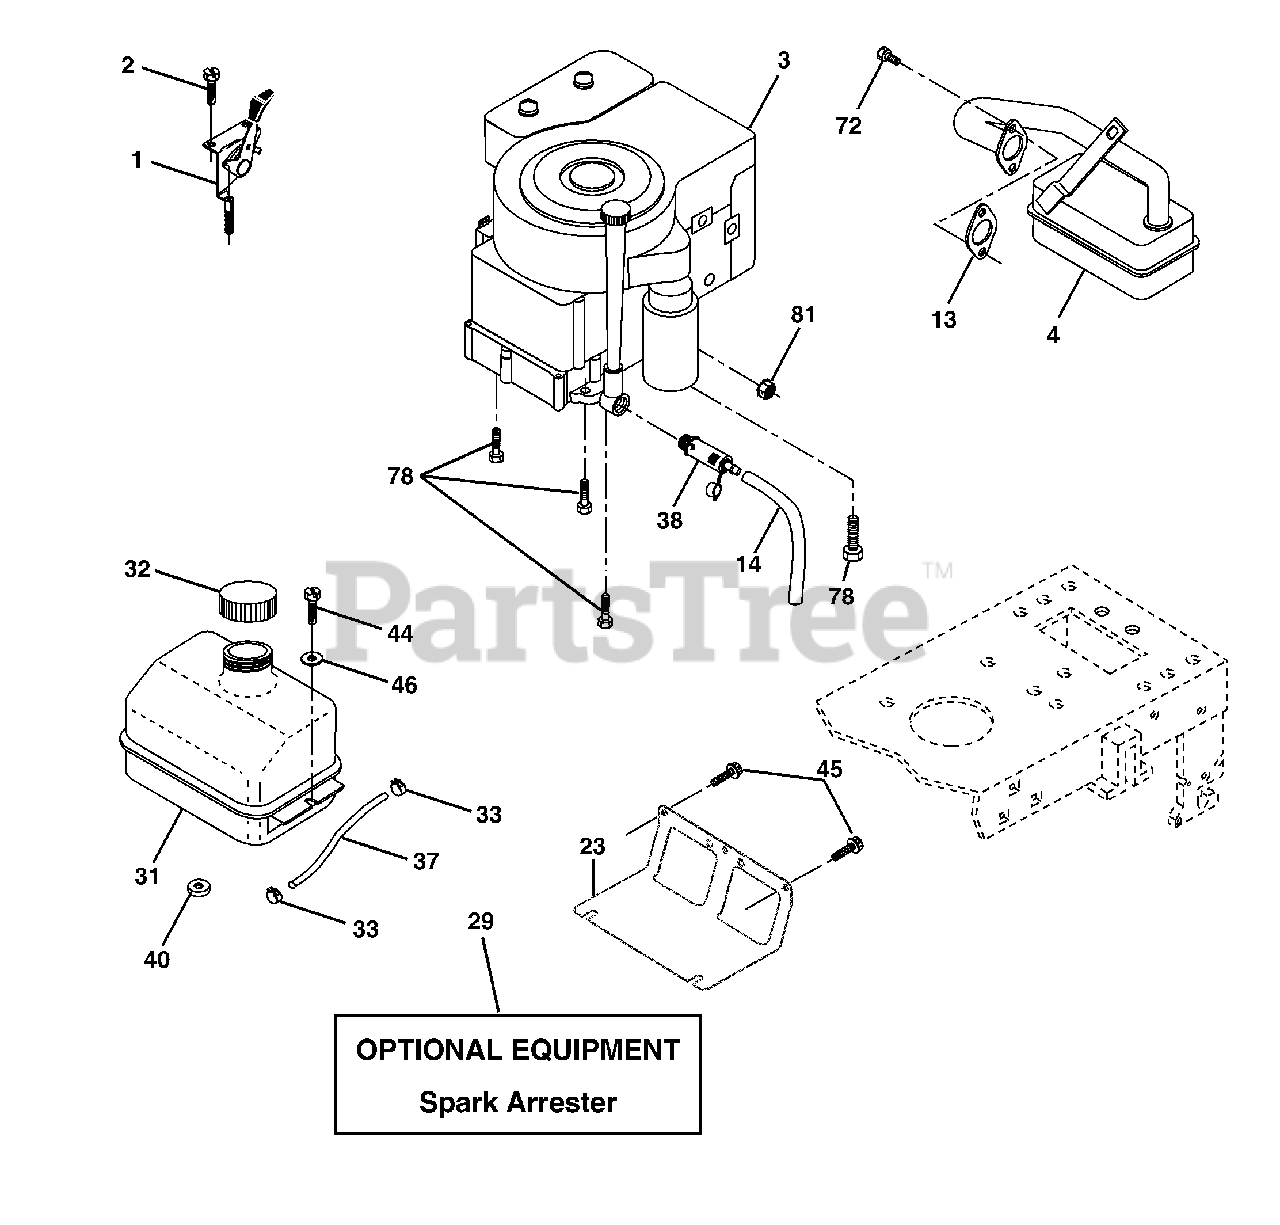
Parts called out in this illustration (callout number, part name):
1	Control Th/ch Flag
2	Screw Hex Thd Cut 1/4-20 x 1/2
4	Muffler Exhaust B&S
13	Gasket Eng 1 313 Id Tin Plated
14	Tube Drain Oil Easy
23	Shield BRN/DBR Guard
29	Kit Spark Arrestor (Flat Scrn)
31	Tank Fuel Front
32	Cap Asm Fuel
33	Clamp Hose
37	Line Fuel 20"
38	Plug Drain Oil
40	Bushing Snap Nyl Blk Fuel Line
44	Screw Thdrol 1/4-20 x 3/4
45	Screw Hex Wsh Thdrol 3/8-16
46	Washer 9/32 x 7/8 x 16 Ga.
72	Screw Scocket Head 5/16-18 x 1
78	Screw 3/8-16 x 1-1/4
81	Nut Keps Hex 1/4-20 unc
